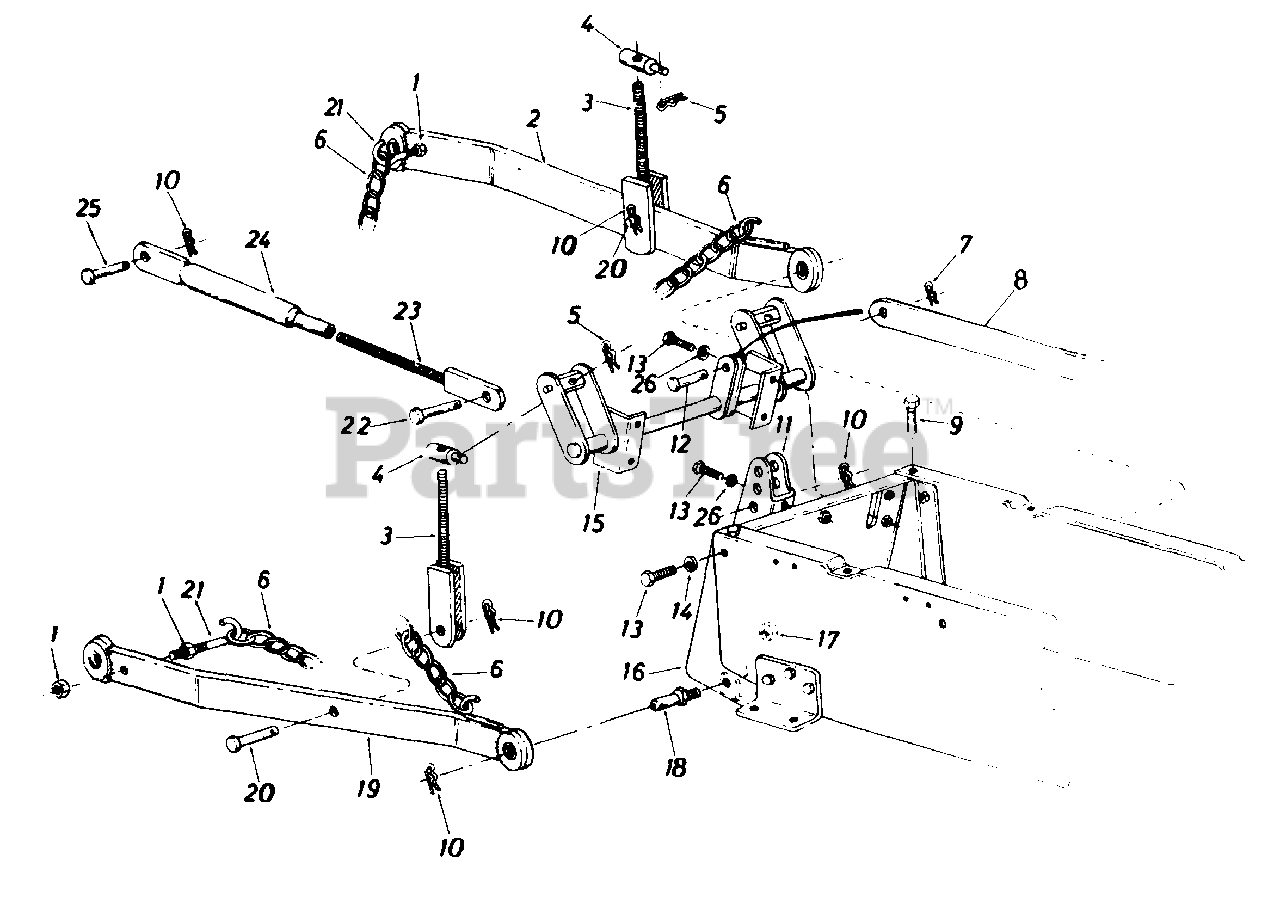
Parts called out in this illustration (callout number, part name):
1	Hex Cent. L-Nut 7/16-14 Thd.
5	Hitch Pin Clip
6	Chain - 20 Links
7	Cotter Pin 1/8" Dia. x 1.25" Lg.
10	Hairpin Cotter
13	Hex Scr. 3/8-16 x .75" Lg.
14	L-Wash. 3/8" Scr. - H.D.
18	Link Clevis Pin
21	Hitch Chain Hook
22	Clevis Pin .63" Dia. x 2.4" Lg.
23	Clevis Screw
25	Clevis Pin .63" Dia. x 2.4" Lg.
26	L-Wash. 3/8" Scr. - H.D.
